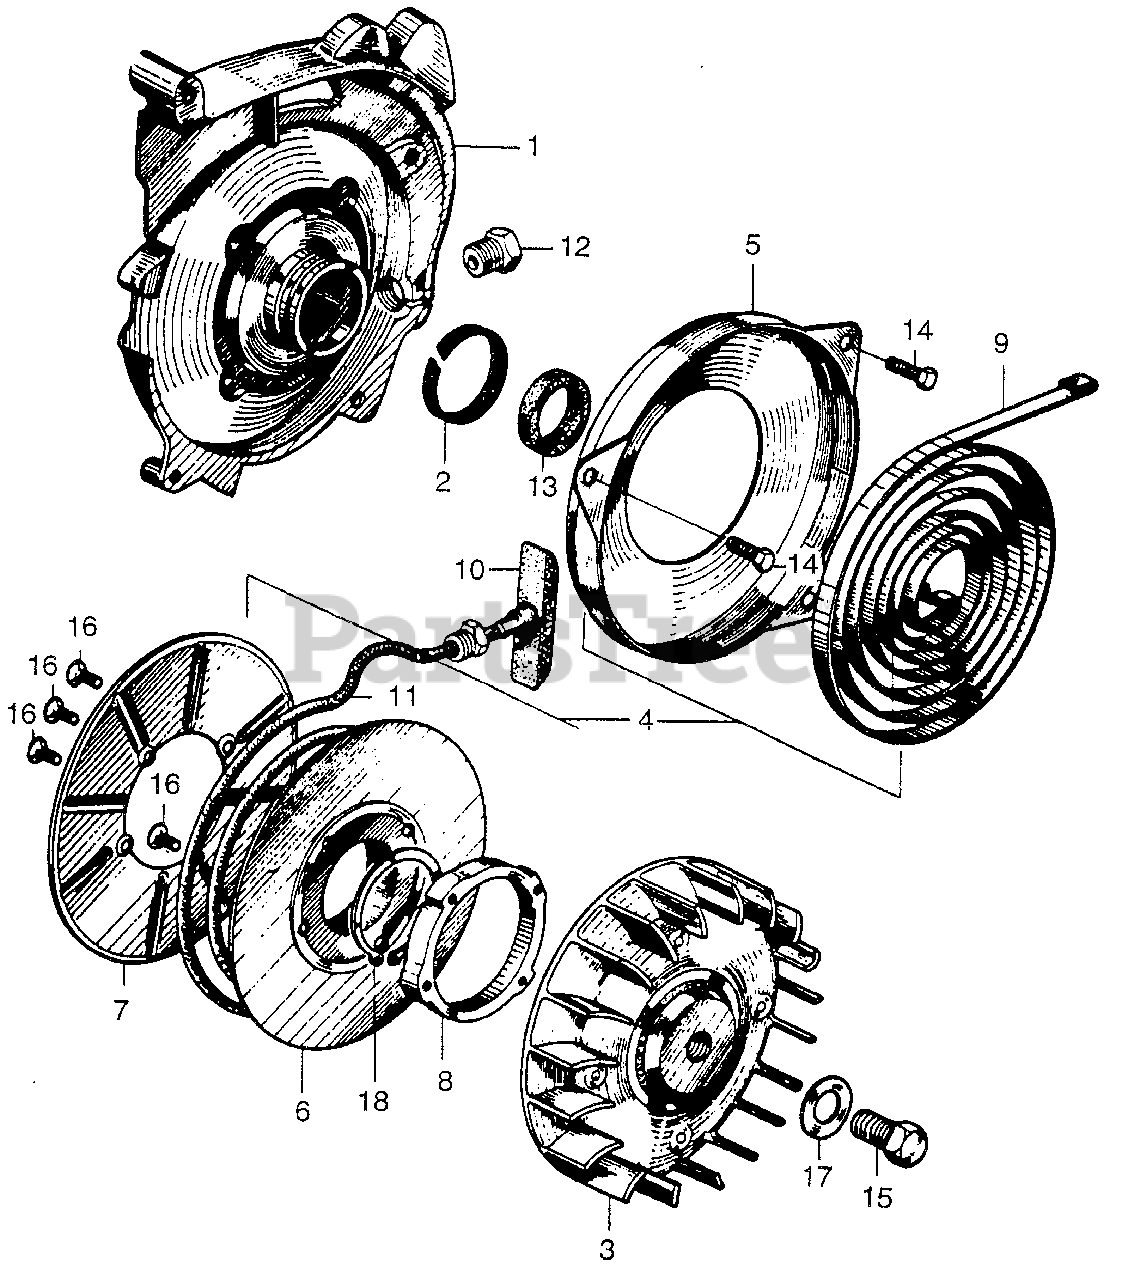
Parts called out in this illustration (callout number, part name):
1	CASE, STARTER
2	FELT (4.5MM)
3	FAN, COOLING (NOT AVAILABLE)
4	STARTER ASSY., RECOIL (NOT AVAILABLE)
5	CASE, SPRING (NOT AVAILABLE)
6	PULLEY, STARTER
7	PLATE, STARTER (NOT AVAILABLE)
8	RATCHET, STARTER (NOT AVAILABLE)
9	SPRING, STARTER RETURN (NOT AVAILABLE)
10	GRIP, STARTER (NOT AVAILABLE)
11	ROPE, STARTER (#5.5X79")
12	GUIDE, ROPE
13	OIL SEAL (15X24X5)
14	BOLT, HEX. (5X10)
15	BOLT, HEX. (8X20)
16	SCREW, FLAT (5X14)
17	WASHER, PLAIN (10MM)
18	CIRCLIP (OUTER) (30MM)
